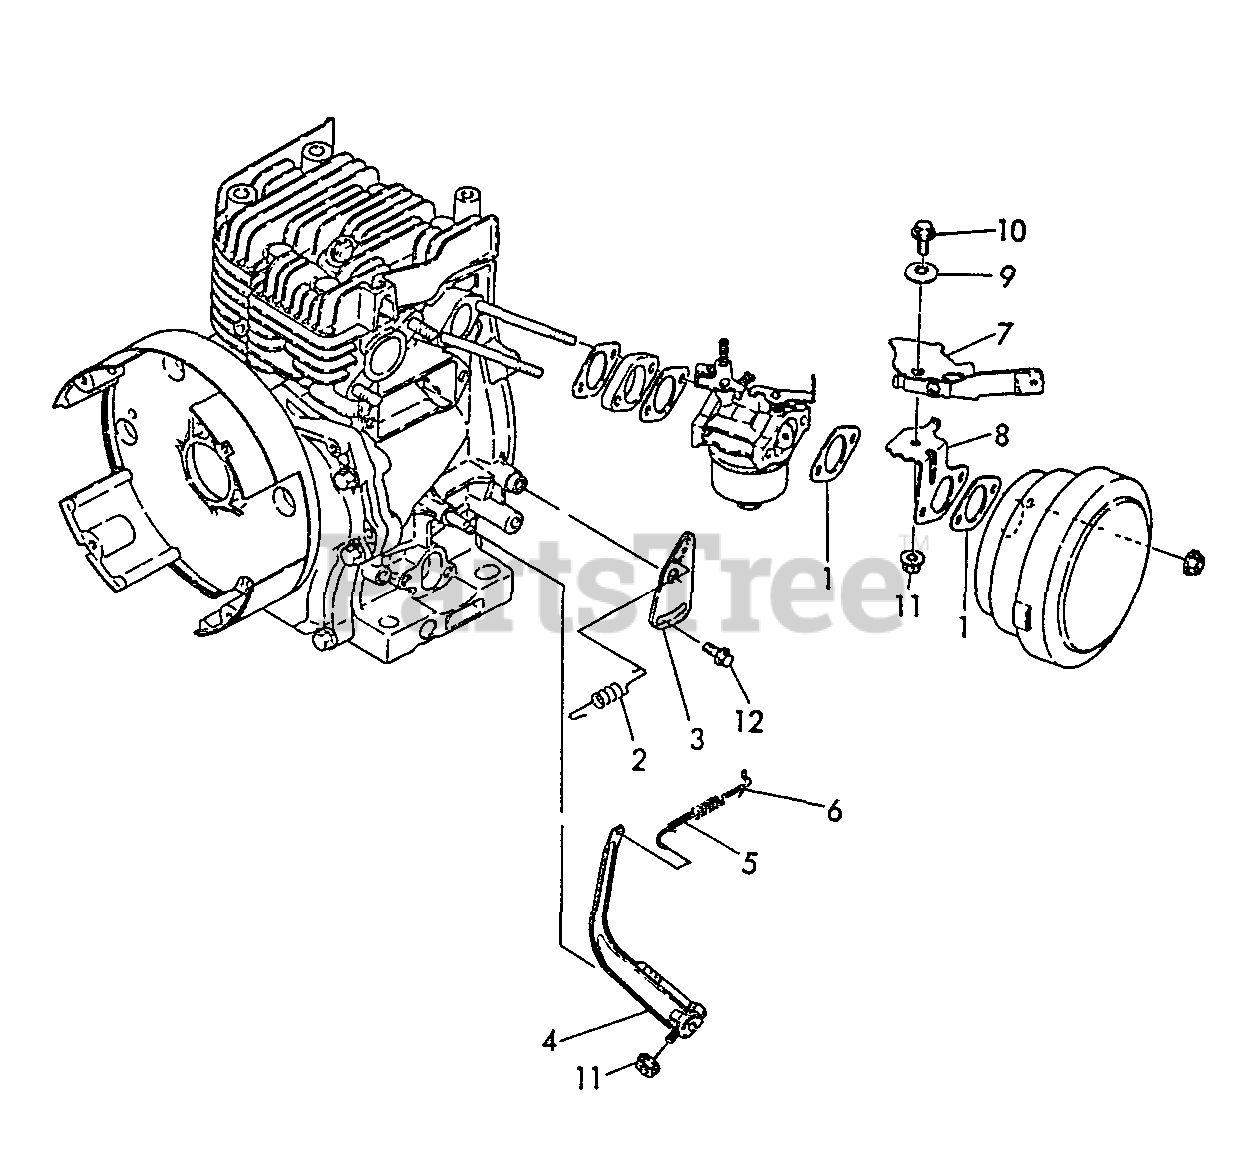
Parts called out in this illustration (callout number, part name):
1	GASKET, INTAKE
2	SPRING, REGULATOR
3	HANDLE, REGULATOR
4	LEVER, GOVERNOR
5	LINK, THROTTLE
6	SPRING, TENSION
7	LEVEL ASSY
8	BRACKET
9	COLLAR
10	BOLT - 6×12 -- PLATED
11	U-NUT M6
12	BOLT - 6×8 -- PLATED
